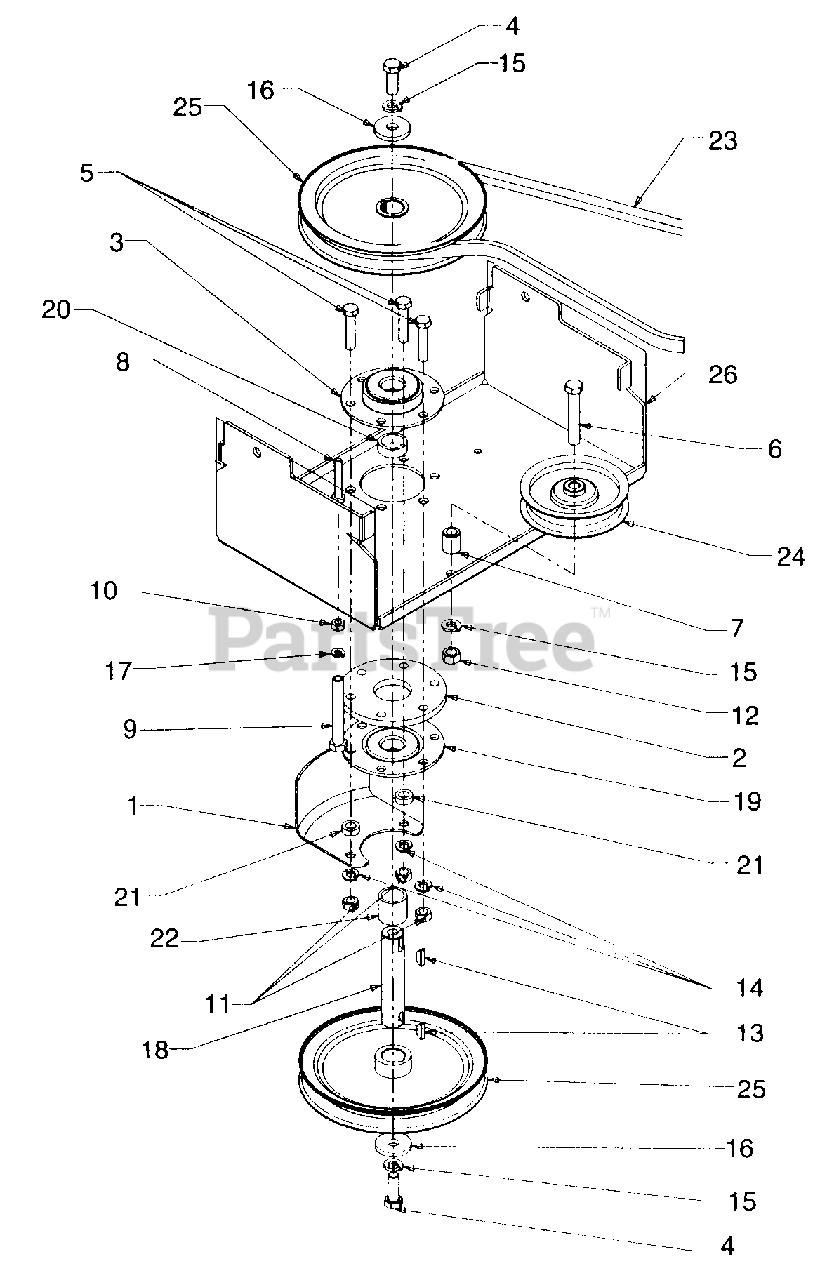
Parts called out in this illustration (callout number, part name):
3	OPEN BRG. HOUSING 1.85
4	HHCS:3/8-24:1.00:GR5:LOCK
5	HHCS:5/16-24:1.50:GR5:STD
6	HHCS:3/8-16:2.25:GR2:STD
7	SPCR:.385 X .623 X .750 LG
8	PIN:GDE:.250 DIA X 1.68 LG
9	PIN:CLEVIS:.375 DIA X 2.63 LG
10	NUT:LOCK:1/4-20
11	NUT:5/16-24:GRA:HX
12	NUT:3/8-16:GRA:HX
13	KEY:HI-PRO 3/16 X 5/8
14	WASH:LOCK:5/16:REGULAR DUTY
15	WASH:LOCK:3/8:REGULAR DUTY
16	FLAT WASHER .406 ID X 1-1/4 OD
17	WASH:LOCK:1/4:REGULAR DUTY
18	SHAFT .787 DIA X 3.81 LG.
19	HSG ASM:BEARING
20	SPACER .790 ID X .347 LG.
21	SPACER .378 ID X .625 OD X .22
22	SPACER .80 ID X 1.00 OD X .900
23	BELT: V: 1/2 X 52.00 LG
24	FL-IDLER W/ FLANGES 3.75 OD
25	PUL:V TYP:6.50 OD
